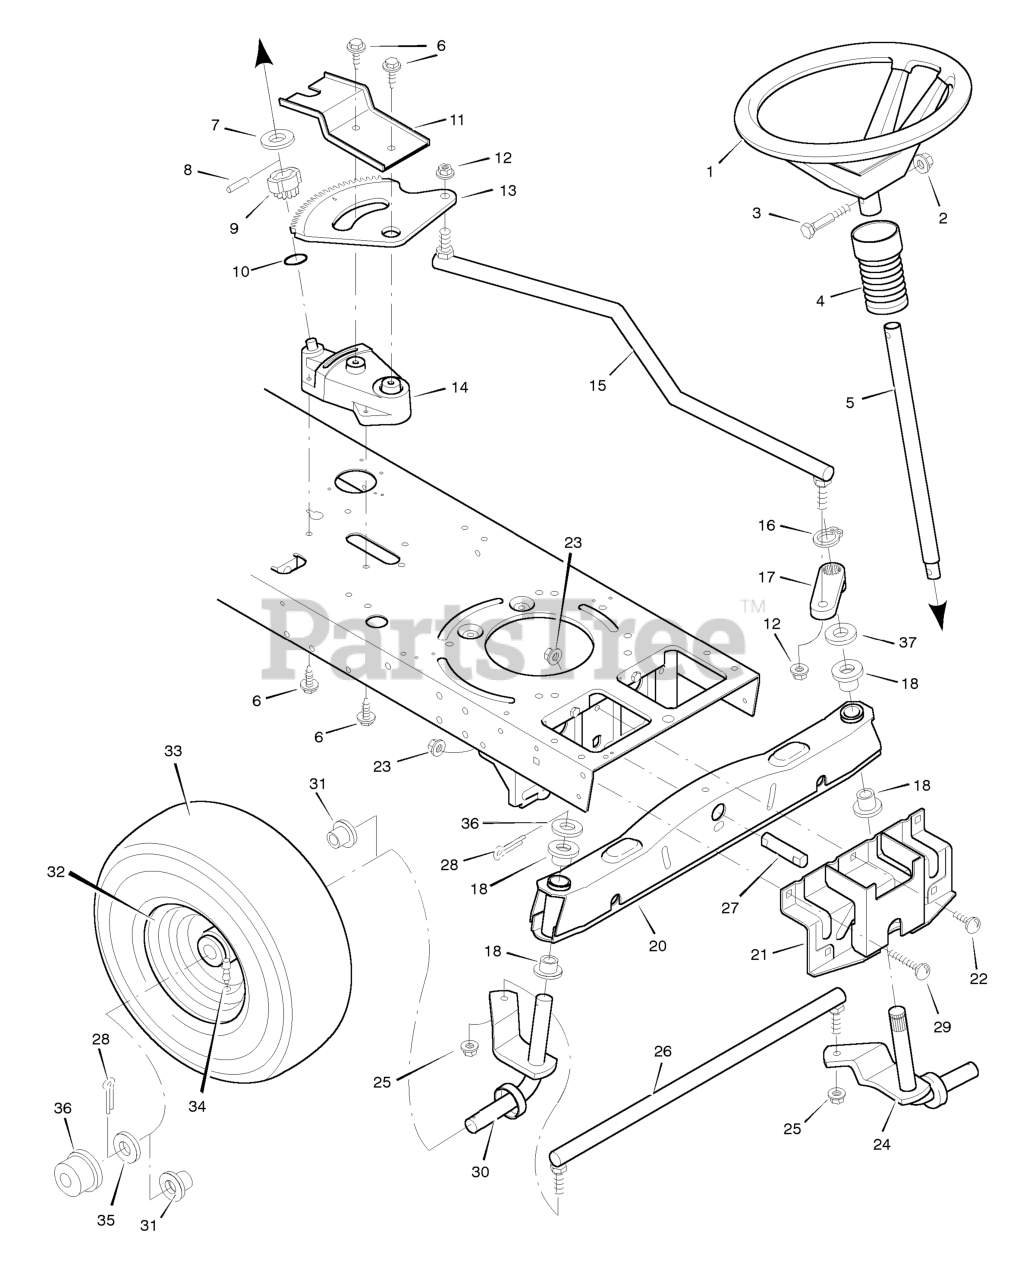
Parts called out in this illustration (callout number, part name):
1	Wheel, Steering
2	Nut, Hex
3	Bolt, Hex
4	Bellows
5	Post Assembly, Steering
7	Washer
8	Pin, Spring
9	Gear Assembly, Pinion
10	O- Ring
11	Clip, Gear Retainer
12	Locknut, Flange
13	Gear, Sector
14	Support, Steering
15	Link, Drag
16	E- Ring
17	Arm, Drag Link
18	Bearing
20	Axle Assembly (with grease fittings)
21	Hanger Assembly, Axle
22	Bolt, Carriage
23	Locknut, Flange
24	Spindle Assembly, Left
25	Locknut, Flange
26	Rod, Tie
27	Pin, Pivot
28	Pin, Cotter
29	Bolt, Carriage
30	Spindle Assembly, Right
31	Bearing, Wheel
32	Wheel & Tire Assembly
33	Tire *
34	Stem, Valve
36	Hub Cap
